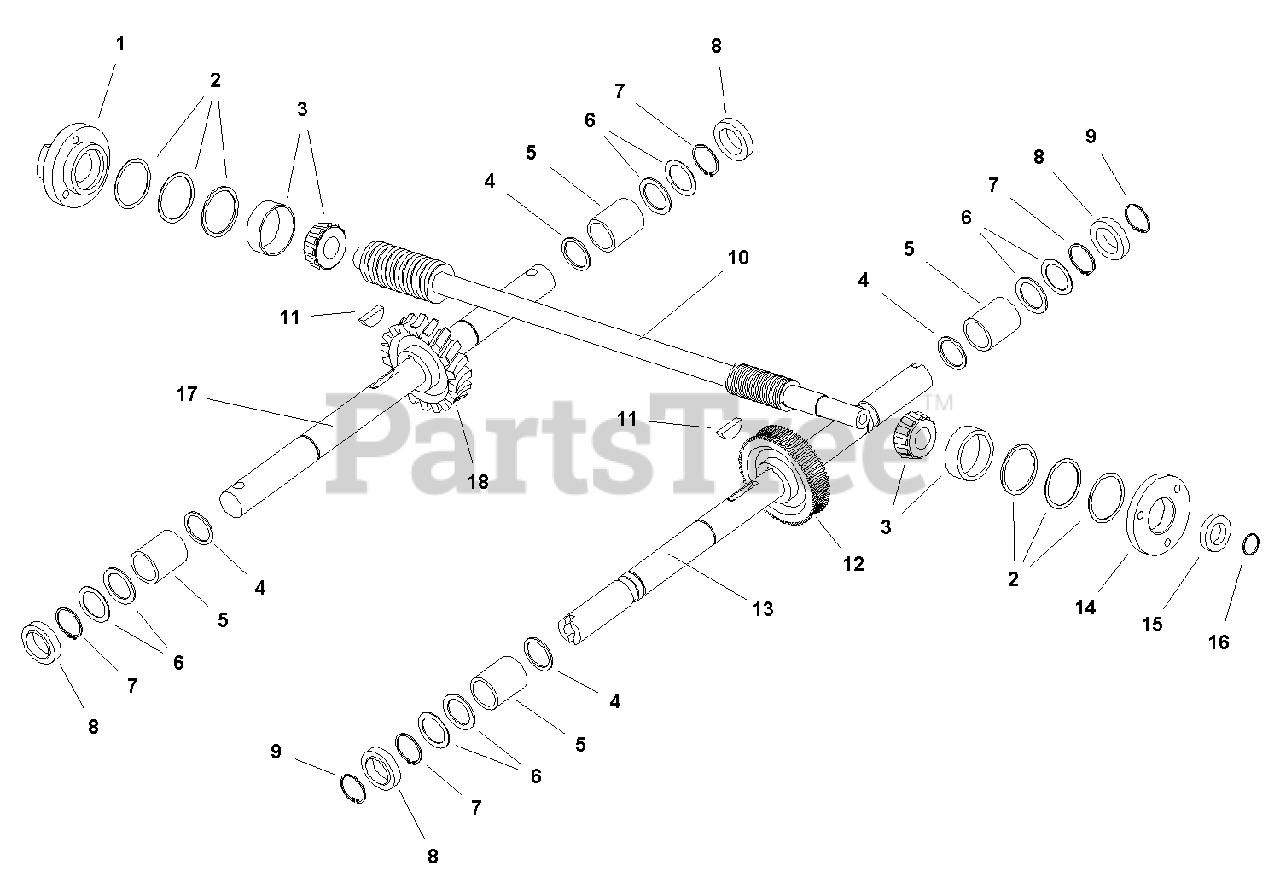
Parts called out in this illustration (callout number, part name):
1	CAP, Rear Bearing
2	SHIM SET, Rear Bearing Cap
2	SHIM, 0.062 THK 1-3/4 OD 1806 (As Required)
2	SHIM, 0.030 THK 1-3/4 OD 1807 (As Required)
2	SHIM, 0.015 THK 1-3/4 OD 1808 (As Required)
2	SHIM, 0.010 THK 1-3/4 OD 1809 (As Required)
3	BEARING, Tapered (Cone & Race)
4	SPACER, 1" ID x 11/4" OD
6	SHIM SET, Axle Spacer
6	SHIM, 0.062 THK 1-3/8" x OD 1705 (As Required)
6	SHIM, 0.030 THK 1-3/8" x OD 1706 (As Required)
6	SHIM, 0.015 THK 1-3/8" x OD 1707 (As Required)
6	SHIM, 0.010 THK 1-3/8" x OD 1708 (As Required)
7	RING, Snap, Internal Retainer
8	SEAL, Housing
9	RING, Snap, External Retainer
10	DRIVE SHAFT, Main
11	KEY, Parrallel Plan 1/4" x 1/4" x 1"
12	GEAR, Worm, Wheel Shaft
13	SHAFT ASSEMBLY, Wheel w/Lock Pin
14	CAP, Rear Bearing
15	SEAL, Oil, Drive Shaft
16	WASHER, 5/8"
17	SHAFT ASSEMBLY, Wheel w/Lock Pin
18	GEAR, Worm Shaft
